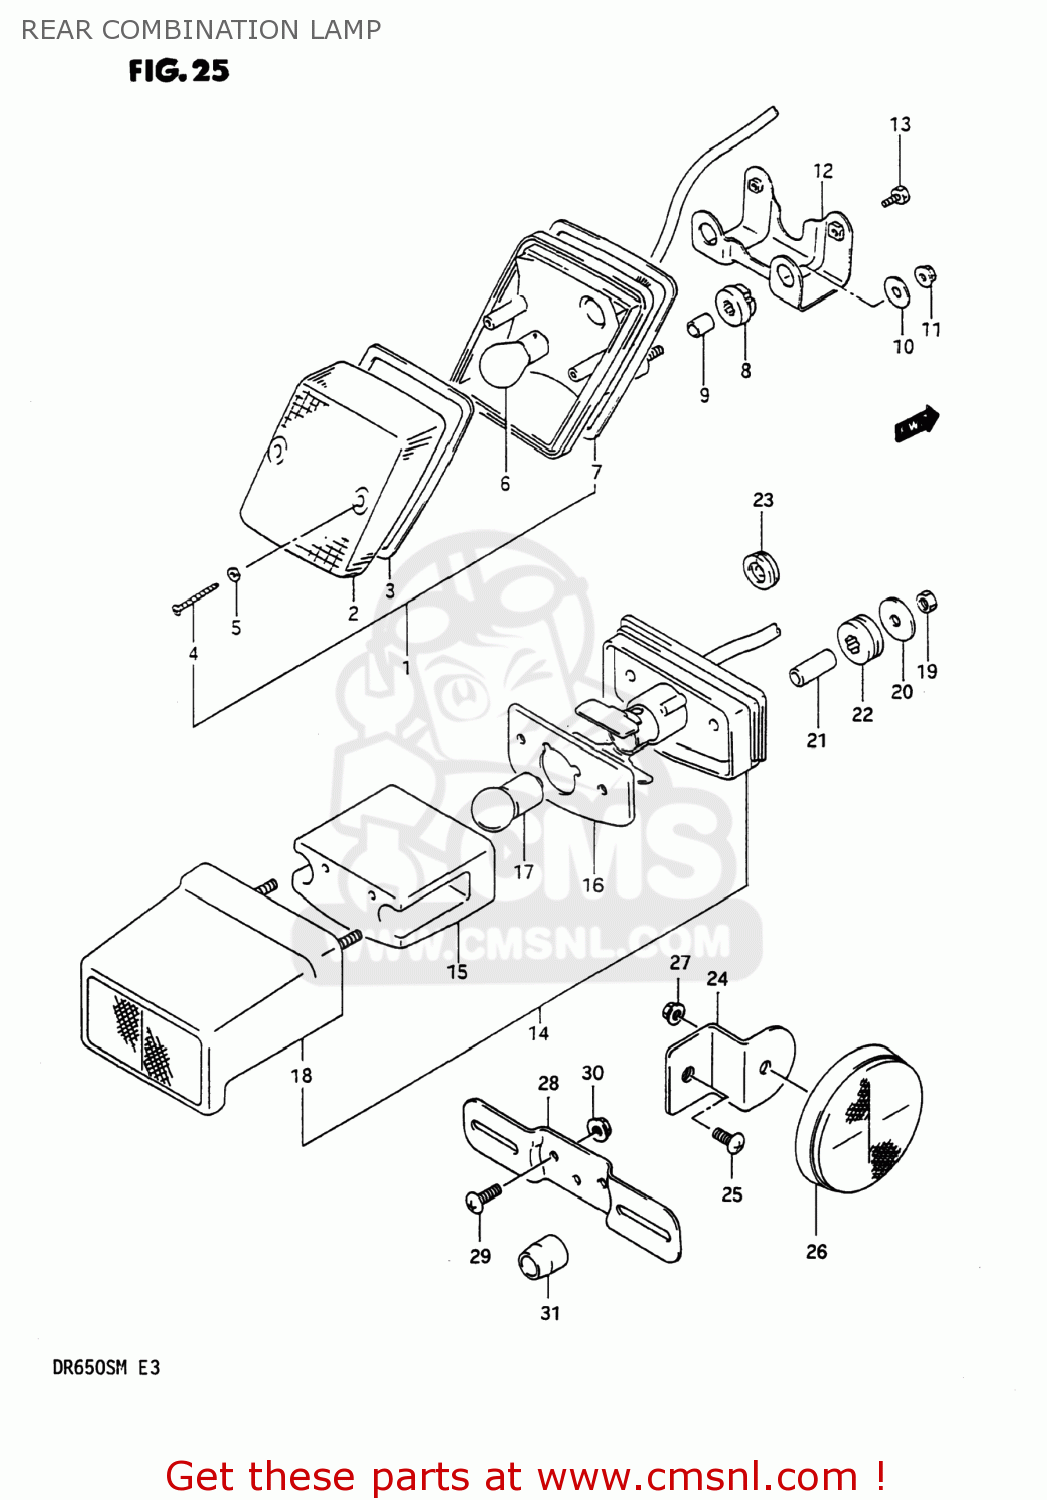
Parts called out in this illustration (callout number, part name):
1	LAMP ASSEMBLY,REAR COMBINATION
2	LENS,RR COMBI
3	GASKET,REAR COMBINATION LAMP
4	SCREW TAPP.
5	GASKET (NAS)
6	BULB(12V23/8W,TOKAI DENSO)
7	GASKET
8	CUSHION
9	SPACER (6.8X10X10)
10	WASHER (6.5X20X1.2)
11	NUT
12	BRACKET,REAR COMBINATION LAMP
13	BOLT
14	LAMP ASSEMBLY,LICENSE
15	LENS
16	GASKET,LICENSE LAMP (NAS)
17	BULB
18	REFLEX REFLECTOR & COVER
19	NUT
20	WASHER(4.3X20X1.4)
21	SPACER
22	CUSHION
23	GROMMET
24	BRACKET,REAR SIDE,REAR,LEFT
25	SCREW
26	REFLEX REFLECTOR,RR
27	NUT
28	BRACKET,LICENSE PLATE
29	SCREW
30	NUT
31	CUSHION
